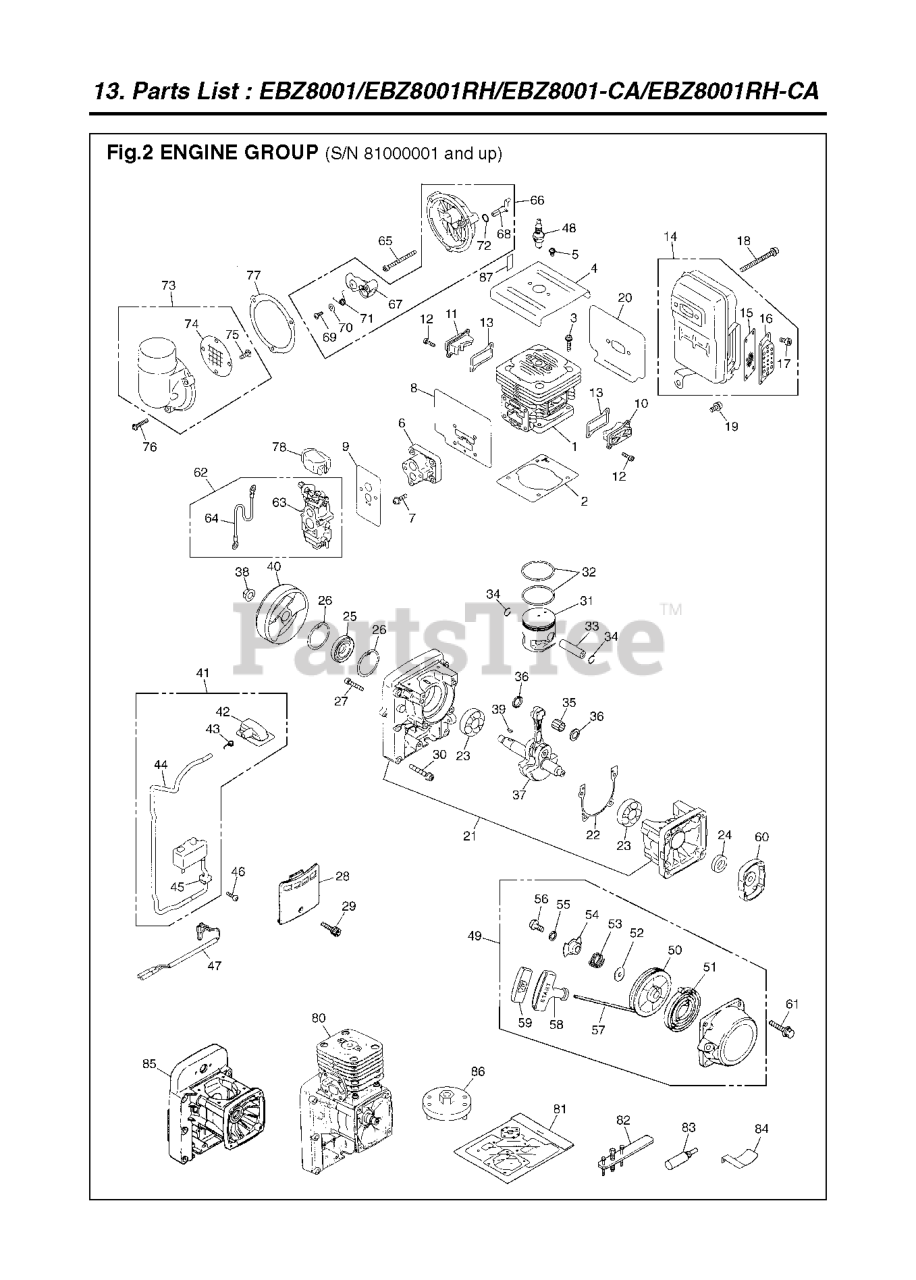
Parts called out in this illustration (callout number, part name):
1	CYLINDER
2	GASKET
3	BOLT
4	PLATE
6	INSULATOR
8	GASKET
10	RP_COVER TR(S)
11	COVER TR(F)
14	MUFFLER-A
15	%ARRESTER
16	RP_DIFFUSER
20	GASKET MUFFLER
21	CRANKCASE COMP.
22	GASKET
23	BALL BEARING
24	SEAL
25	SEAL
26	SNAP-RING
28	COVER
30	BOLT
31	PISTON
32	RING.PISTON
33	PISTON PIN
34	SNAP RING
35	ROLLER BEARING
37	SHAFT COMP
39	KEY
40	ROTOR
41	COIL ASSY.(RPLS 848H107120)
43	SPRING
44	RP TUBE-A
45	GROMMET
47	CORD-COMP
48	PLUG CMR7H
49	RECOIL ASSY
50	REEL
52	WASHER
53	SPRING FRICTION
54	PLATE
57	ROPE
58	KNOB
59	COVER
60	PULLEY ASSY
62	CARBURETOR SET
63	CARBURETOR-A
64	CORD
66	CUP ASSY
67	CHOKE PLATE
69	SCREW
70	RP_WASHER
73	CUP COVER ASSY
74	SCREEN
80	SHORT BLOCK
81	GASKET KIT
82	PULLER ASSY
85	RP_CRANKCASE-A
86	RP_PULLER
87	LABEL,CHOKE
